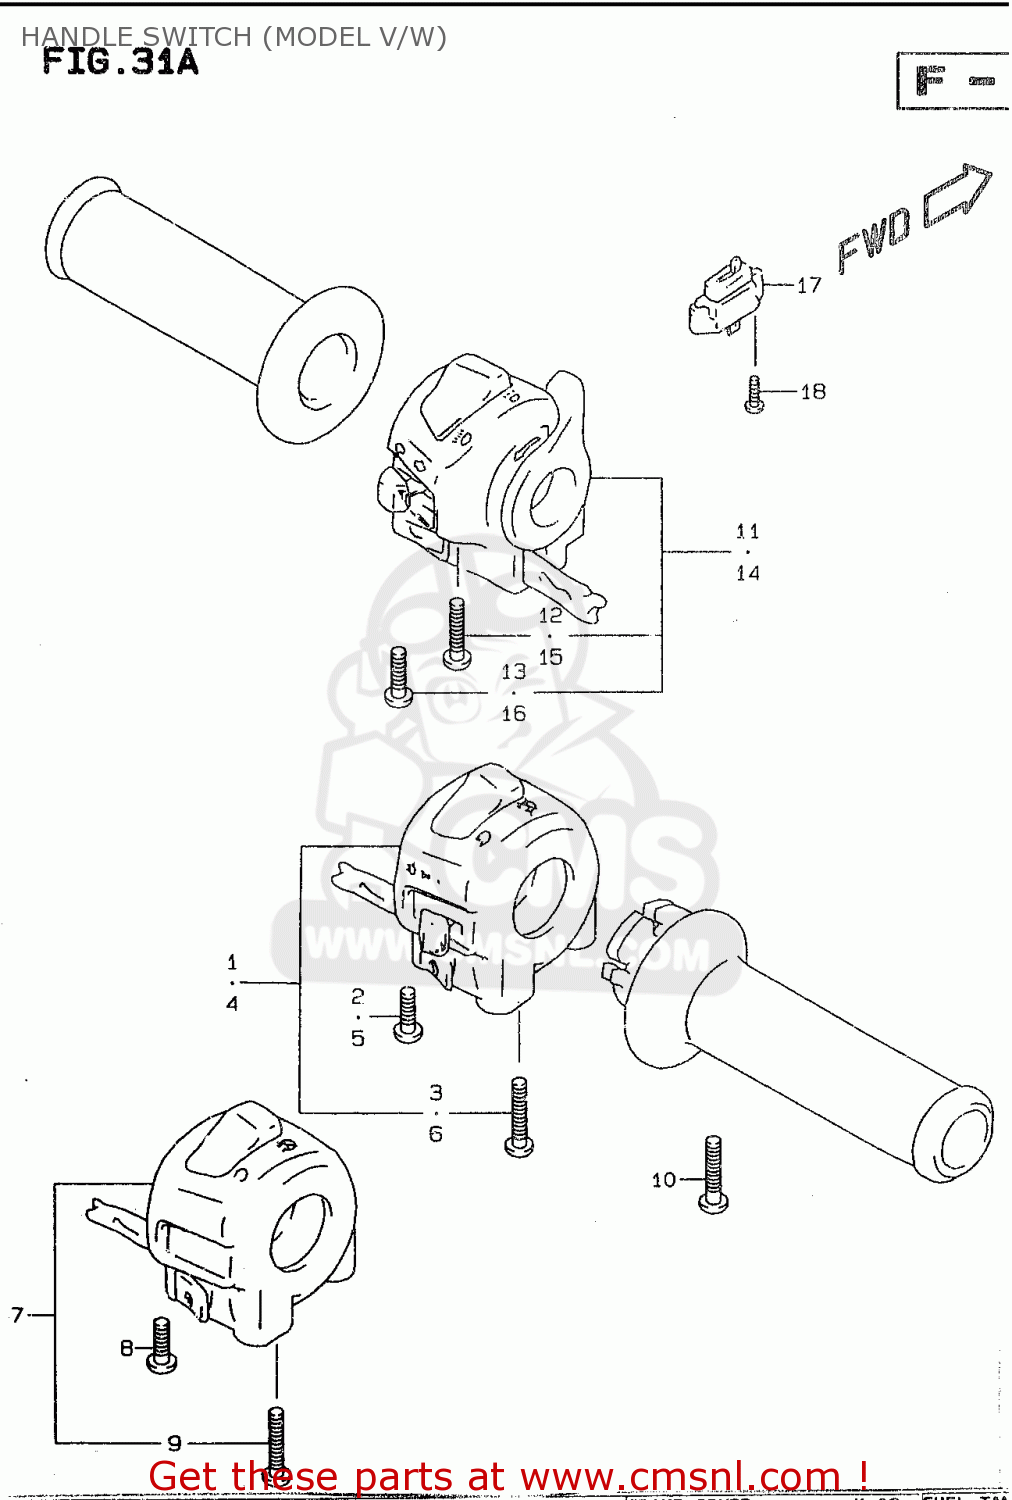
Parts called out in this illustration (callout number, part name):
1	SWITCH,HANDLE,
2	SCREW
3	SCREW
4	SWITCH ASSY,HANDLE,R
5	SCREW
6	SCREW
7	SWITCH ASSY,HANDLE,R
8	SCREW
9	SCREW
10	SCREW
11	SWITCH ASSY,HANDLE,L
12	SCREW
13	SCREW
14	SWITCH,HANDLE,
15	SCREW
16	SCREW
17	SWITCH ASSY,CLUTCH
18	SCREW
